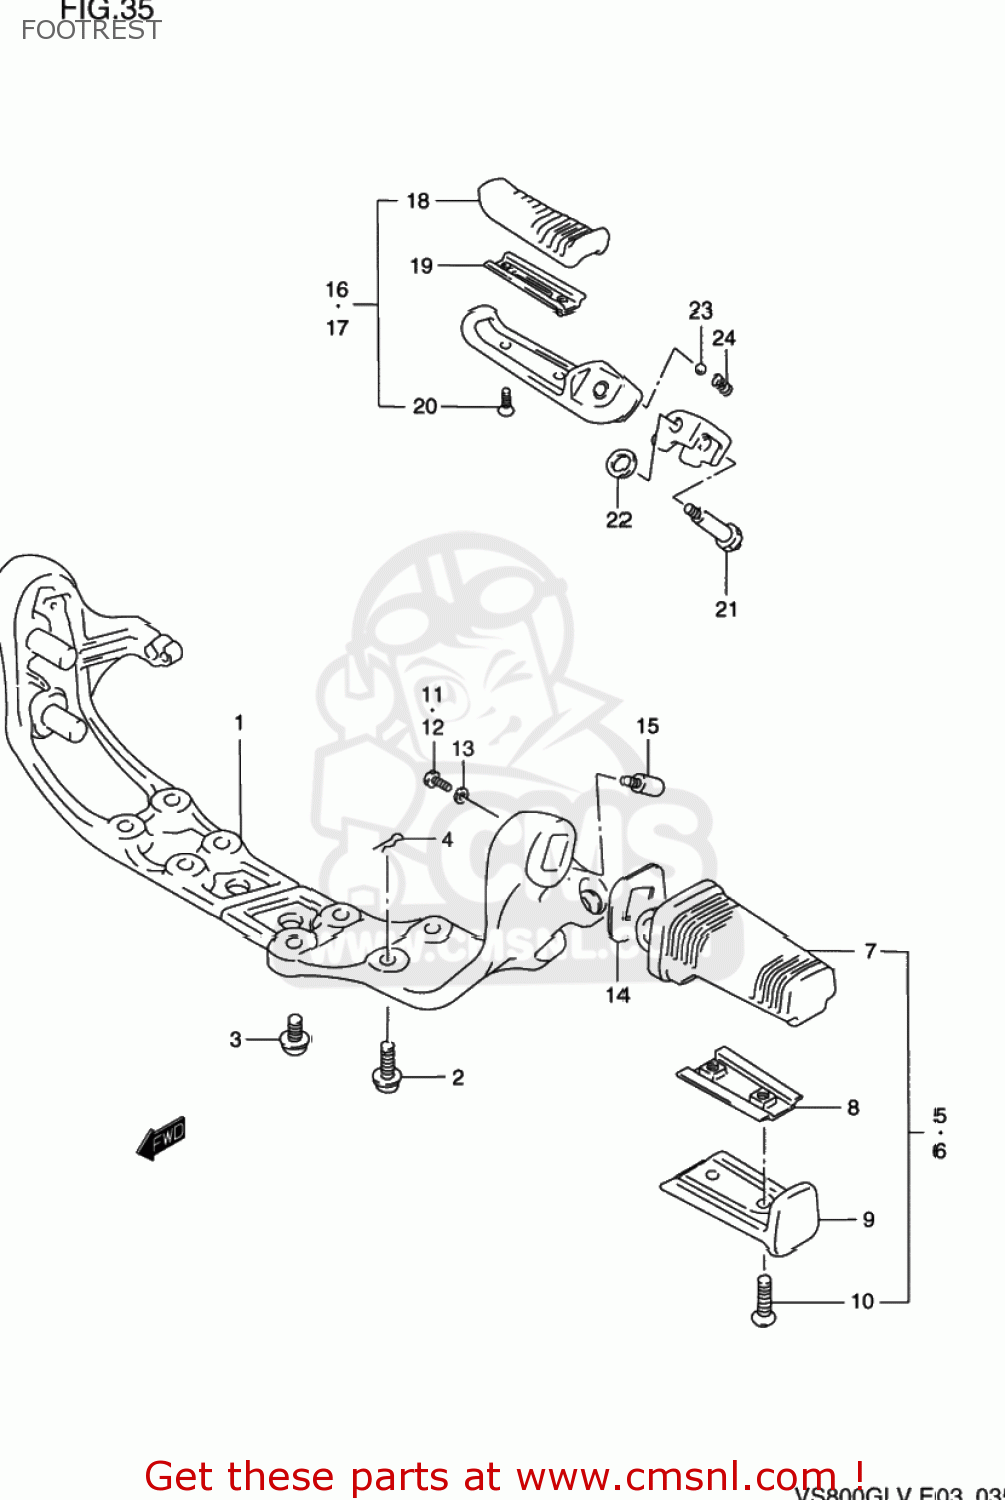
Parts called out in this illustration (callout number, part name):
1	BRACKET,FR FOOTREST
2	BOLT(8X25)
3	BOLT
4	SNAP
5	FOOTREST ASSY,FR,R
6	FOOTREST ASSY,FR,L
7	RUBBER,FR FOOTREST
8	PLATE,RUBBER STOPPER
9	COVER,FR FOOTREST
10	SCREW(5X20)
11	BOLT
12	SCREW
13	WASHER,LOCK
14	WASHER,FR FOOTREST
15	BOLT,FRONT FOOTREST
16	FOOTREST ASSY RH
17	FOOTREST ASSY PILLION LH
18	RUBBER,PILLION FOOTREST
19	PLATE,RUBBER STOPPER
20	SCREW(5X16)
21	BOLT(6X34.5)
22	SHIM
23	BALL
24	SPRING
